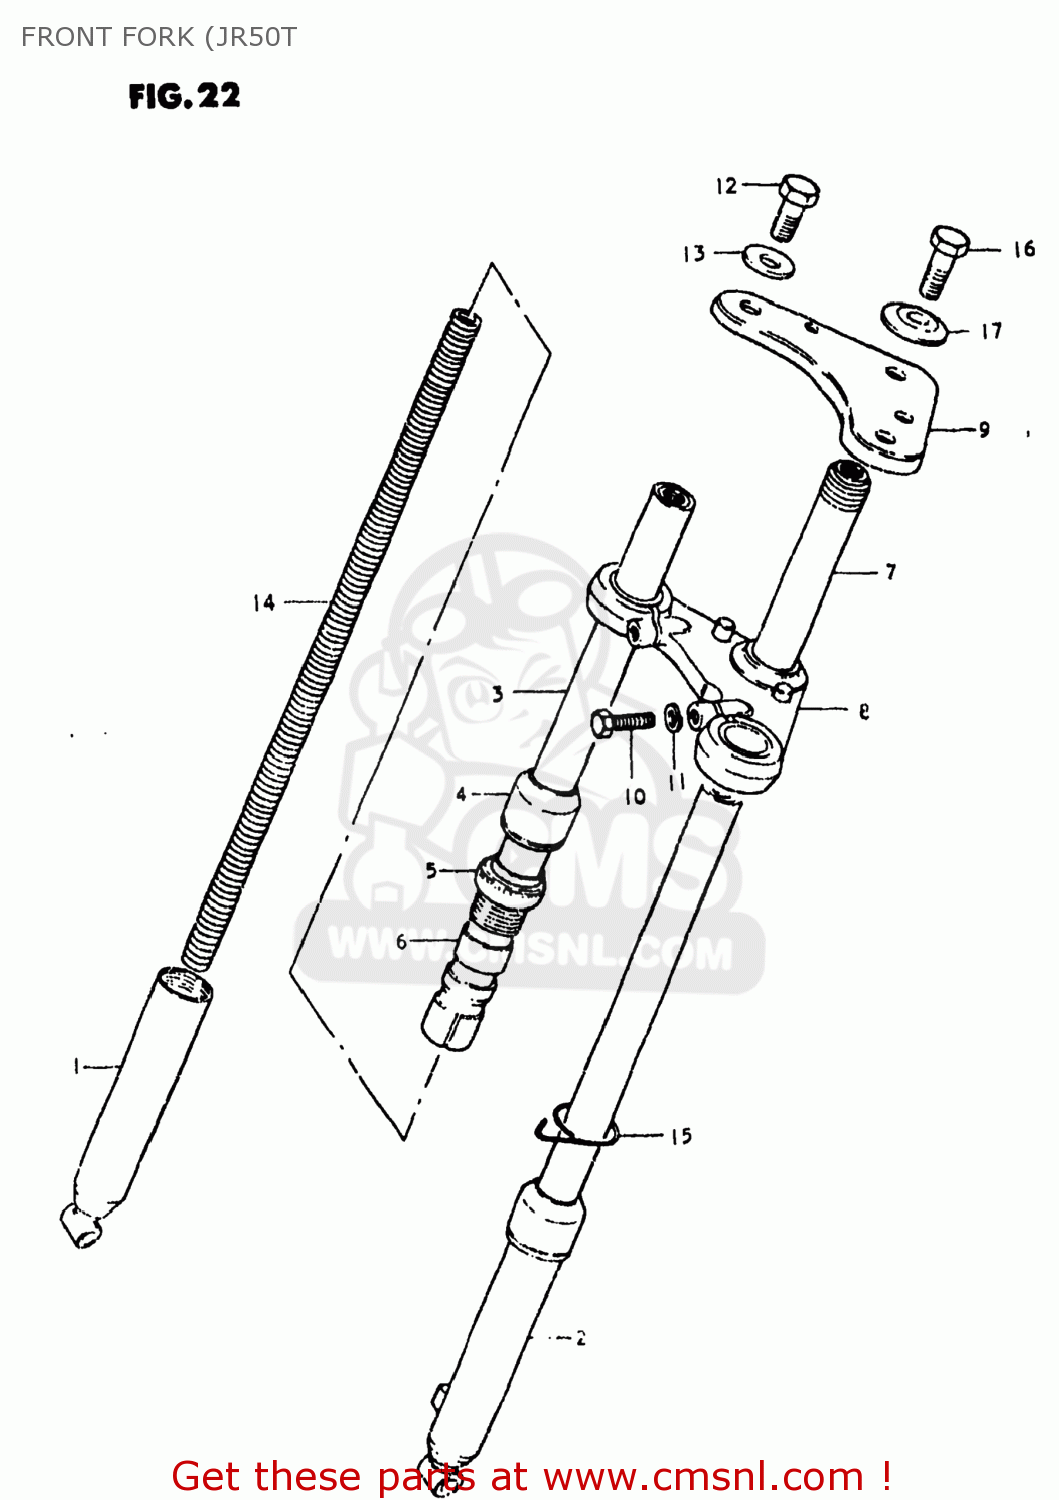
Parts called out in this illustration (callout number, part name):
1	TUBE,OUTER,RIGHT
2	TUBE,OUTER,LEFT
3	TUBE,FORK,INNER
4	SEAL,DUST
5	NUT,OUTER
6	STOPPER
7	STEM,STEERING
8	RACE,STEERING,OUTER,LOWER
9	HEAD,STEERING STEM
10	BOLT
11	LOCK WASHER
12	BOLT,FRONT FORK,UPPER
13	WASHER,STEERING STEM HEAD
14	SPRING
15	CLIP
16	CAP,FORK INNER TUBE
17	WASHER
